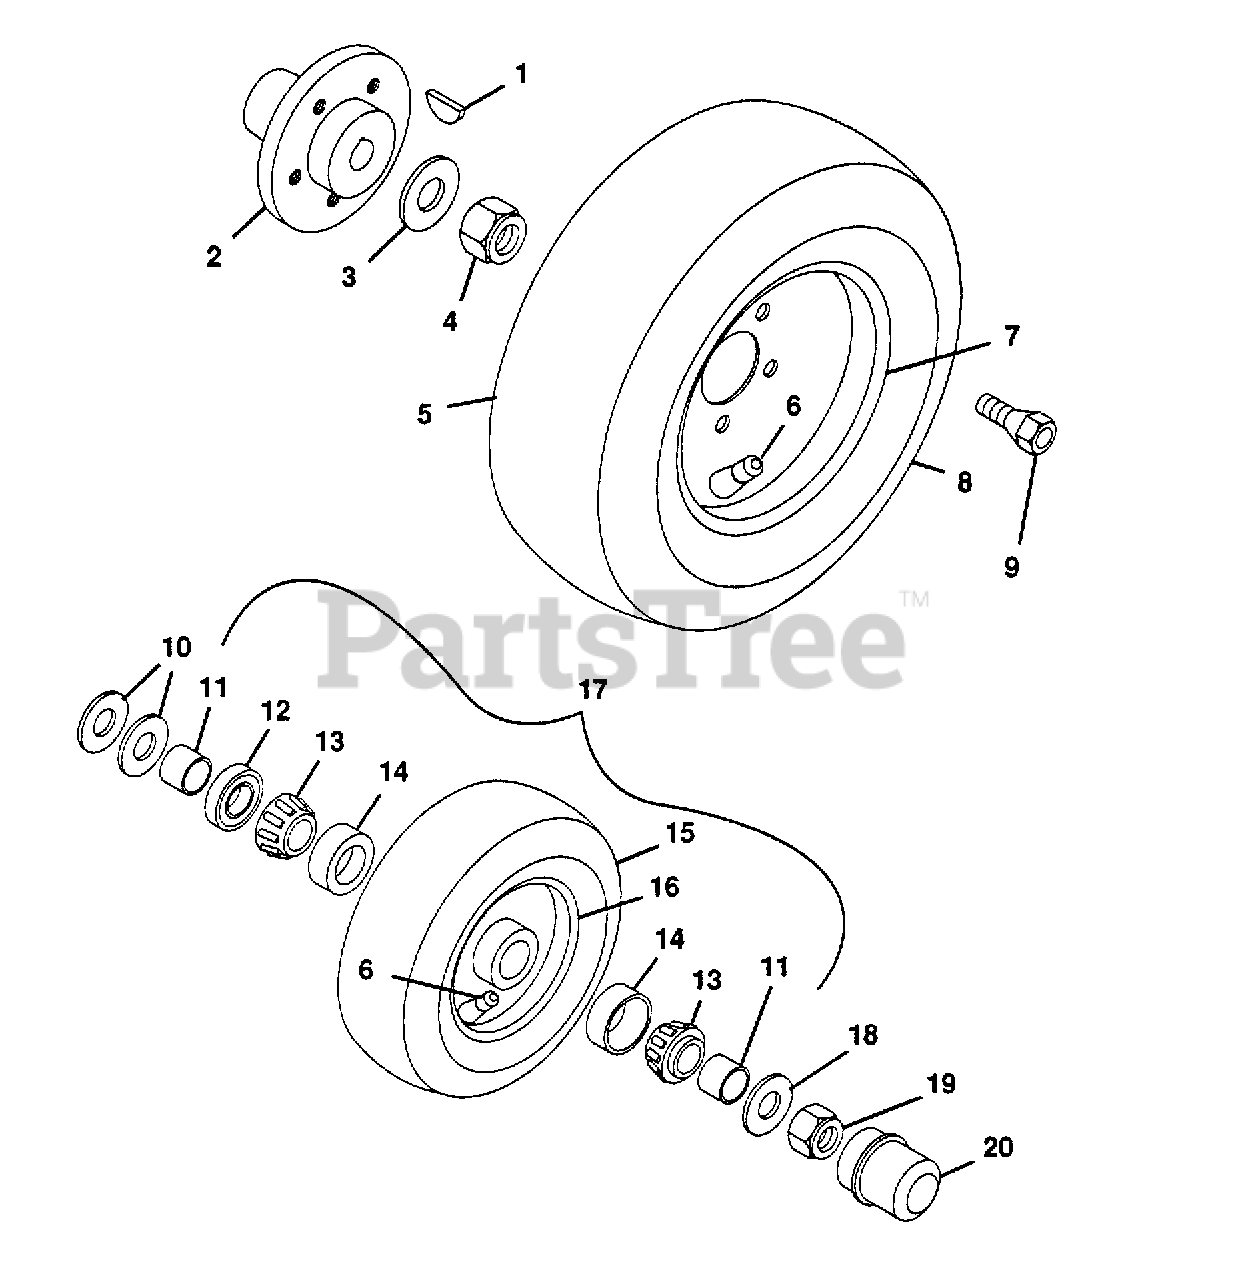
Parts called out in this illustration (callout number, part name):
1	KEY, WOODRUFF .312X2.125
2	HUB, TAPERED
3	WASHER, FLAT .813X2.0X.148
4	NUT, LOCK 3/4-10
5	ASSEMBLY, WHEEL 26X12-12
6	ASSEMBLY, VALVE STEM
7	WELDMENT, RIM REAR
8	TIRE, REAR 26X12-12
9	BOLT, HUB 7/16-20X.75(SPECIAL)
10	WASHER, FLAT .813X1.37X.100
11	SPACER
12	SEAL, OIL
13	BEARING, CONE LM 11949
14	BEARING, CUP LM 11910
15	TIRE, FRONT 18X8.50-8
16	WELDMENT, RIM FRONT
17	ASSEMBLY, WHEEL 18X8.50-8
18	WASHER, FLAT .656X1.312X.095
19	NUT, LOCK 5/8-11
20	CAP
